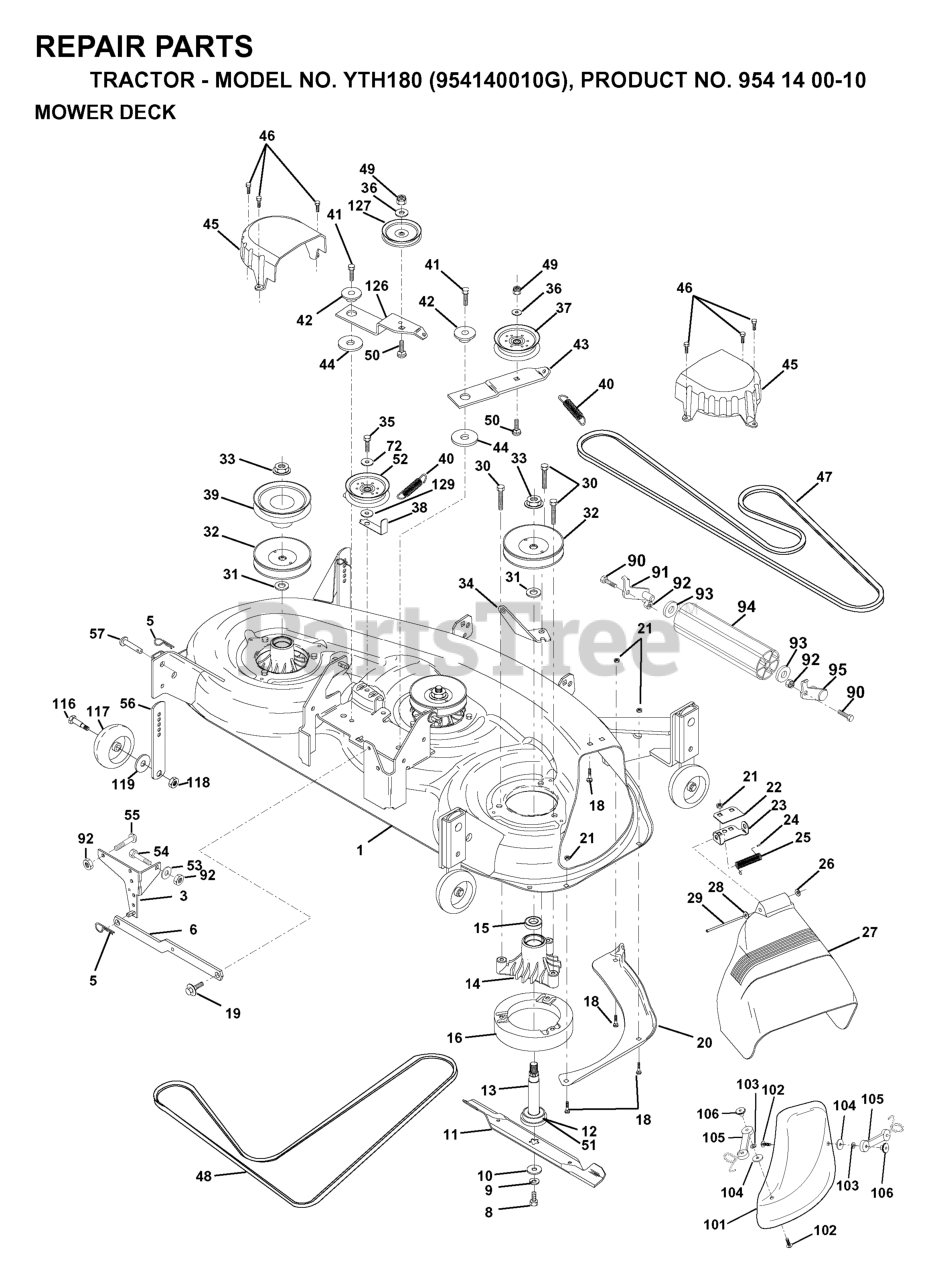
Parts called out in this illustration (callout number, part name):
3	BRACKET SWAY BAR
5	RETAINER-SPRNG RB
6	REAR SUSP ARM
8	BLADE BOLT
9	LOCKWASHER
10	WASHER.BLADE
11	MULCH BLADE
12	BEARING.BALL.#6204.(MANDREL)
13	SHAFT.ASM.W/BEARING
14	HOUSING.MANDREL.44/46" VENT
16	STRIPPER
18	BOLT
19	BOLT SHD 5/16-18
20	BAFFLE, VORTEX MOWER 46"
21	LOCKNUT
22	STIFFENER BRACKET
23	DEFLECTOR BRACKET
24	CAP-SLEEVE LT
25	TORSION SPRING
26	NUT PUSH M
27	DEFLECTOR SHIELD
28	Washer 11/32 x 5/8 x 16 Ga SD
29	ROD.HINGE
30	SCREW THDROL ROLLING WASHER HD
31	WASHER
32	PULLEY, MANDREL
33	NUT
34	ANCHOR, SPRING DECK 46"
35	SCREW LT
36	WASHER
37	FLAT IDLER PULLEY
38	KEEPER.BELT.IDLER
39	PULLEY.DRIVEN.DECK.46"
40	SPRING.SEC.44"VEN
41	SCREW
42	SPACER RETAINER
43	ARM IDLER DECK 46"
44	HARDENED WASHER
45	COVER MANDREL 46
46	SCREW.1/4-20X5/8
47	BELT V SECONDARY
48	V-BELT PRIMARY 50"
50	BOLT.3/8-16X1.50
51	WASHER FELT
52	PULLEY IDLER FLAT 46 PRI DRIVE
53	WASHER
55	BOLT D
56	BAR.ADJUST.WHEEL.ANTI.SCALP.BL
57	RIVET.PIN.HEAD.YELLOW.
72	WASHER
90	BOLT
91	BRACKET LH (A)
92	NUT
93	Washer 1 17/32 X 7/8 X 16 Ga
94	NOSE ROLLER
95	BRACKET RH (B)
101	COVER.MULCH.46"3-BLADE.(2 2)
102	SCREW
103	LOCKWASHER #10
105	LATCH ASSY
106	WELDNUT
116	BOLT, SHOULDER
117	WHEEL GAGE DONUT
118	LOCKNUT
119	WASHER.5/16.FLAT.STE.STD.
126	ARM IDLER PRIM 46
127	PULLEY.IDLER.4.25
129	Washer 13/32 x 1-3/8 x 13 Ga.
